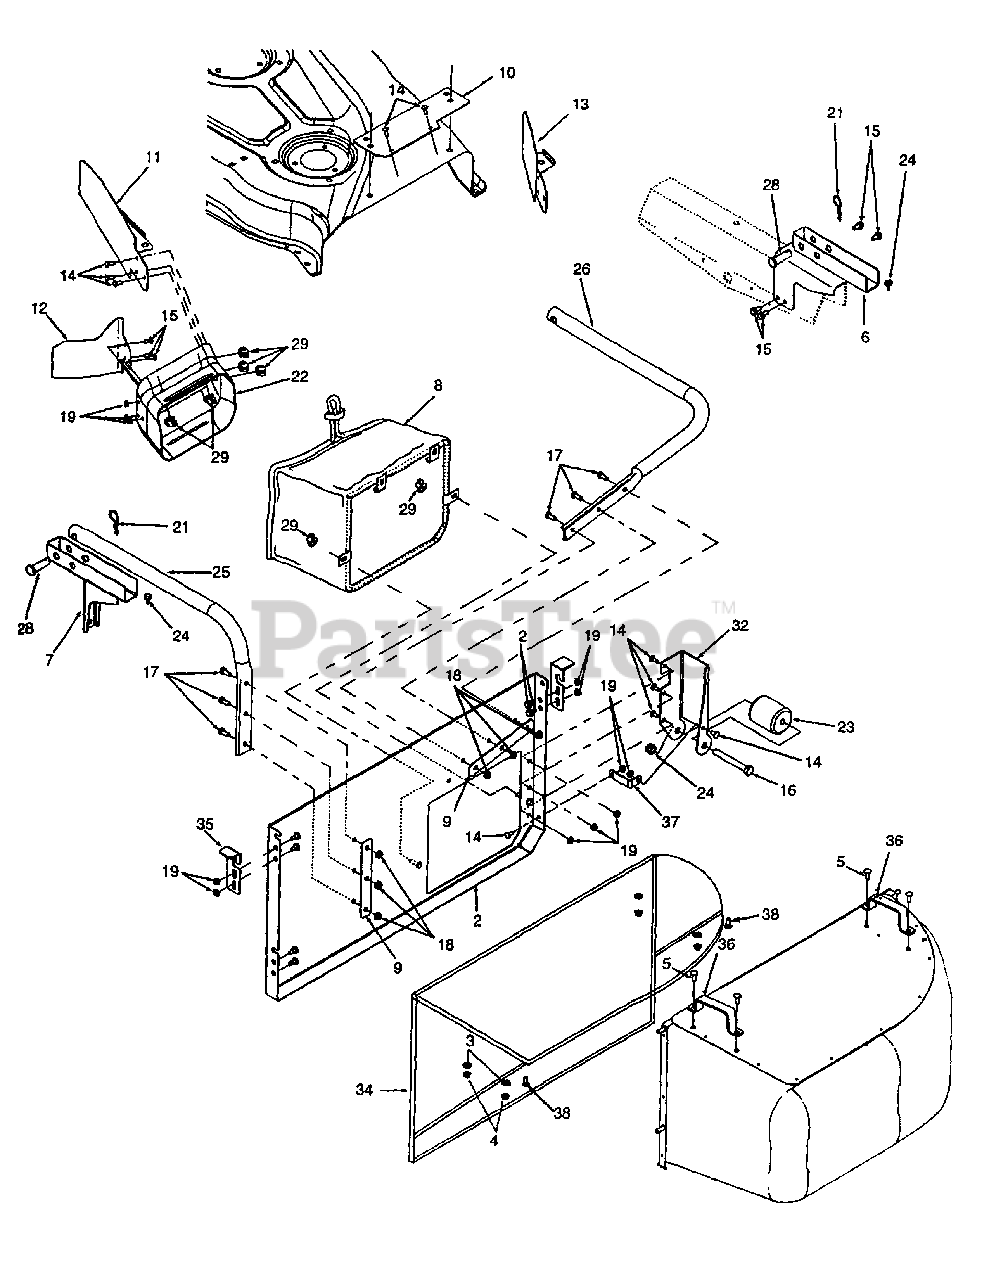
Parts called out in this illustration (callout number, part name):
1	Lock Nut, Nylon Insert, #10-24
2	Round Head Screw, 10-24 x 1/2
3	Flat Washer, 5/16
4	Nylock Nut, 5/16-18
5	HHCS, 5/16-18, 1-1/4
6	Front Support Bracket Assembly
7	Rear Support Bracket Assembly
8	Grass Bag
9	Plate Support Tube Assembly
10	Chute Mounting Bracket
11	Baffle, Front Deck 48"
12	Baffle, Rear Deck 48
13	Baffle, Front Deck 54"
14	Bolt, Carriage, 1/4-20 x 5/8
15	Screw: Tapping: 5/16-18 x 5/8
16	HHCS, 1/2-13, 4.00
17	HHCS, 5/16-18,.75
18	Flange Nut, 5/16-18
19	Hex Flange Lock Nut, 1/4-20
20	Hex Lock Nut, 1/2-13
21	Internal Cotter Pin
22	Grass Catcher Discharge Chute
23	Grass Catcher Roller
24	Rubber Bumper, .62 OD x .22 Thick
25	Grass Catcher Support Tube
26	Grass Catcher Support Tube
27	Grass Bag Collector
28	Clevis Pin, 3/8 x 1.687
29	Wing Nut w/Belle Washer 1/4-20
30	Label, Chute
31	Catcher, Panel Assembly
32	Grass Catcher Mount Roller Bracket
33	Bag Release Latch Left Hand
34	Grass Bag Support Frame Assembly
35	Bag Release Latch Right Hand
36	Grass Bag Handle
37	Grass Catcher Support Roller
38	Screw 1/4-20 x 5/8
